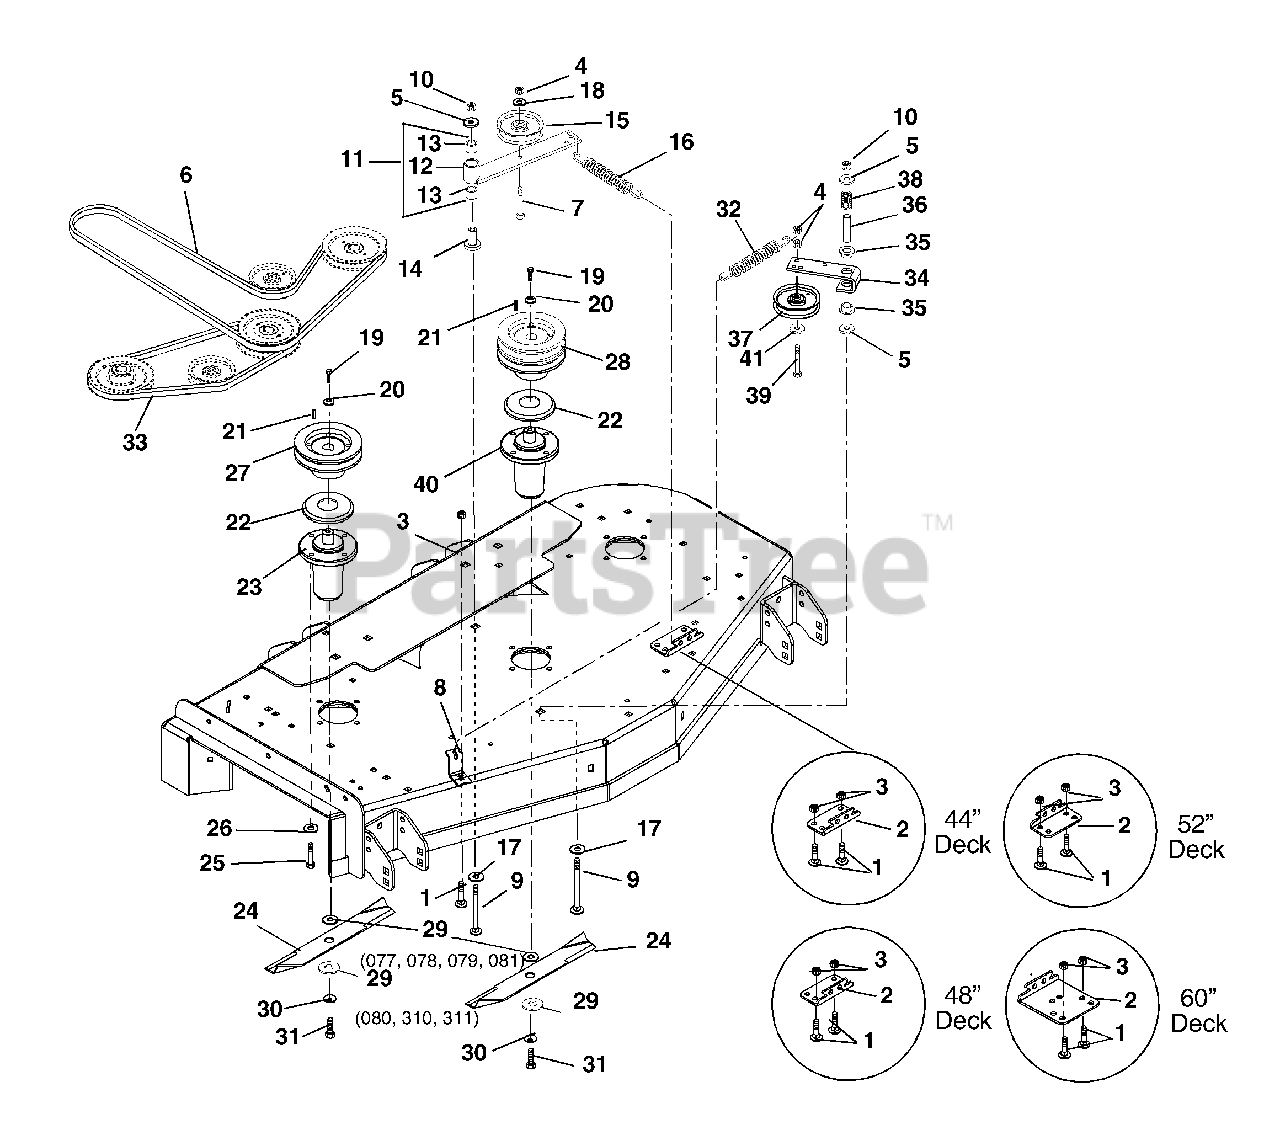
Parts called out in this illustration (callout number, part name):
1	Bolt, Round Head Square Neck .38-16 x .75 Grade 5 (077, 078, 079, 081, 310, 311)
1	Bolt, Round Head Square Neck .38-16 x 1.25 Grade 2 (080, 082)
2	Bracket, Spring (077, 078, 079, 081, 310, 311)
2	Bracket, Spring (080, 082)
3	Nut, Locking Top Flange .38-16
4	Nut, Locking Center .38-16
5	Washer, Flat Steel .531 x 1.25 x .10
6	V-Belt, B-Section 51.50 x .625 (077, 079, 081, 310)
6	V-Belt, B-Section 55.75 x .625 (080, 082)
6	V-Belt, B-Section 48.80 x .625 (078, 311)
7	Bolt, Hex .38-16 x 2.75 Grade 5
8	Anchor, Spring
9	Bolt, Round Head Square Neck .50-13 x 3.50 Grade 5
10	Nut, Locking Top Flange .50-13
11	Assembly, Idler Pivot Arm
12	Weldment, Idler Pivot Arm
13	Bearing, 1.00 x 1.12 x .75
14	Bearing, Pedestal Powdered Metal
15	Idler, Flat 4.00 x .38 (2.00 W)
16	Spring, External .09 x 1.00 x 6.00
17	Washer, Flat Steel .755 x 1.375 x .062 (077, 078, 079, 081, 082, 310, 311)
18	Washer, Flat Steel .375 x 1.125 x .065
19	Bolt, Hex .38-16 x 1.00 Grade 8
20	Washer, Cupped Serrated .375
21	Key, Square .25 x .25 x 1.00 RC 40-50
22	Slinger, Dust
23	Assembly, Maintenance Free Spindle
24	Blade, Mower (18.00) (079, 081)
24	Blade, Mulching (18.00) (079, 081)
24	Blade, Mower 60" (080, 082)
24	Blade, Mower 60" Tungsten Mulch (080, 082)
24	Blade, Mower (077, 078)
24	Blade, 32" (16.25) (310, 311)
24	Blade, Mulching (077, 078)
25	Bolt, Hex .38-16 x 1.00 Grade 5
26	Washer, Locking .38 x .094 Regular
27	Weldment, Spindle Sheave 5.00 (077, 078, 079, 081, 310, 311)
27	Weldment, Spindle Sheave 6.00 (080, 082)
28	Sheave, Double (5.25) (077, 078, 079, 081, 310, 311)
28	Sheave, Double (6.25") (080, 082)
29	Washer, Flat .64 x 1.81 x .250
30	Washer, Bellville .63 x 1.625 x .14
31	Bolt, Hex .62-18 x 1.75 Grade 8
32	Spring, Extension
33	V-Belt, B-Section 19.10 x .672 (079, 081)
33	V-Belt, B-Section 23.94 x .625 (080, 082)
33	V-Belt, 5L-Section 49.97 x .672 (077, 078, 310, 311)
34	Arm, Idler Pivot
35	Bushing, Flange .762 x 1.00 x .58 x 1.48 Nylon
36	Spacer .56 x .75 x 2.44 Steel
37	V-Idler, 4.00 x .38
38	Spring, Compression .085 x .80 x 1.00
39	Bolt, Hex .38-16 x 2.25 Grade 5
40	Spindle Assembly (Center)
41	Washer, Flat Steel .406 x .812 x .065
